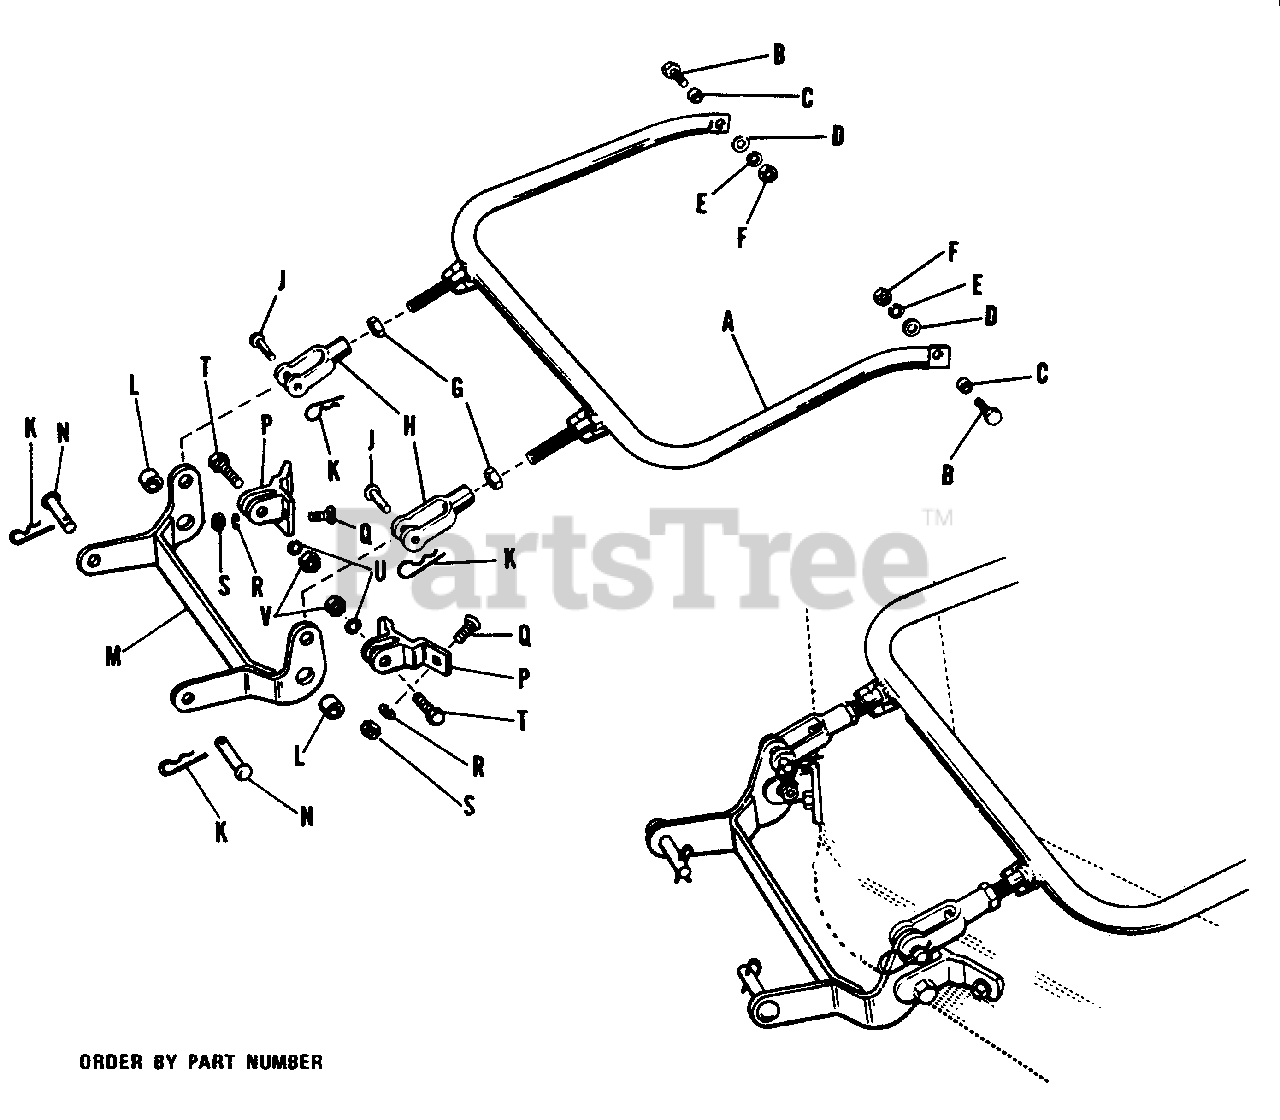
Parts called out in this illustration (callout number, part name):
A	Bail Assembly
B	Capscrew, Hex Hd., 1/2"-13 NC x 1 1/4" lg.
D	Washer, Plain, 7/16
E	Washer, Lock, 1/2"
F	Nut, Hex, Full, 1/2"-NC
G	Nut, Hex, Jam, 1/2"-NF
H	Yoke End, Adjusting
K	Clip, Spring
M	Rocker Arm
N	Pin
P	Bracket Assembly, Front
Q	Bolt, Carriage, 3/8"-16 NC x 1"
R	Washer, Lock, 3/8"
S	Nut, Hex, Full, 3/8"-16 NC
T	Capscrew, Hex, 1/2"-13 NC x 1 1/4"
U	Washer, Lock, 1/2"V
V	Nut, Hex., Full, 1/2"-13 NC
